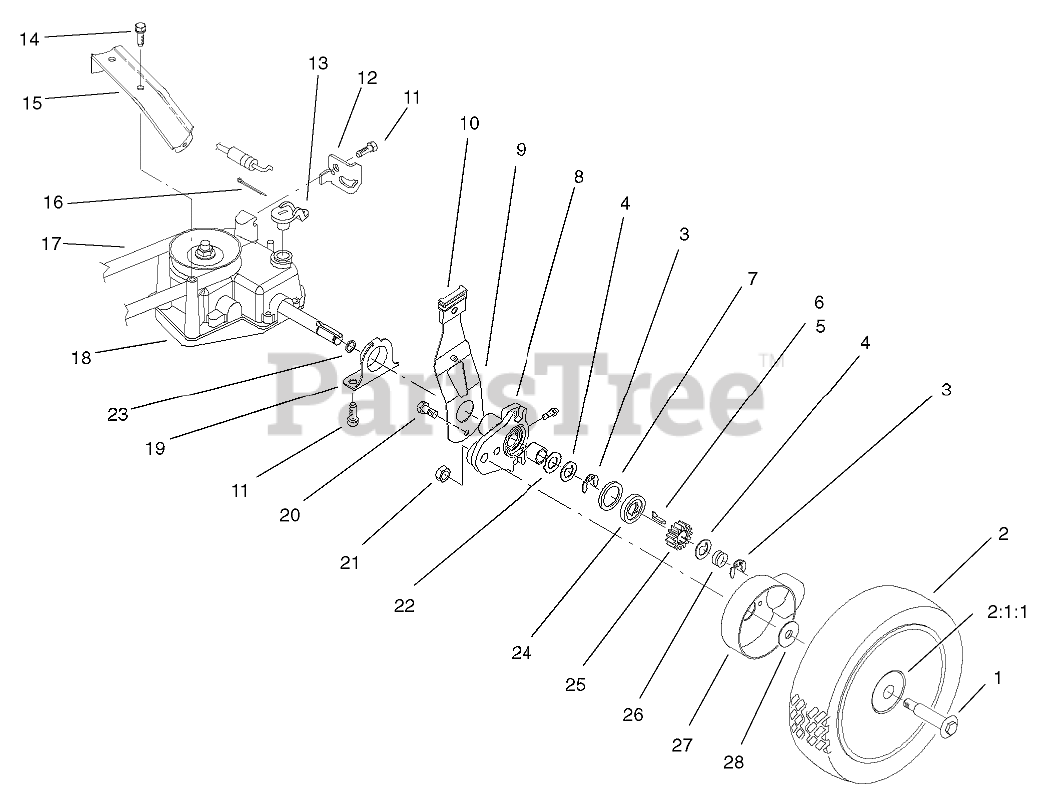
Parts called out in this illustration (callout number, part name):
1	BOLT-SHOULDER
2	WHEEL AND GEAR ASM
2:1	Wheel ASM
2:1:1	BUSHING
3	RING-CLIP, LOCKING
4	WASHER-THRUST, KEYED
5	KEY-ROCKING, LH
6	KEY-ROCKING, RH
7	RING-FRICTION
8	PIVOT ARM ASM
9	SPRING ARM ASM
10	KNOB-ARM
11	SCREW-HWHTF
12	RETAINER-CABLE
13	LEVER-SHIFT
14	SCREW-HWHTF
15	BRACKET-GUIDE, BELT
16	PIN-COTTER
17	V-BELT
18	GEARCASE ASM
19	CAP-END
20	SCREW-HWH
22	WASHER-ARM, PIVOT
23	O-RING
24	WASHER-CLUTCH
25	GEAR-PINION
26	SPRING-COMPRESSION
27	COVER-WHEEL
28	SPACER-COVER, WHEEL
